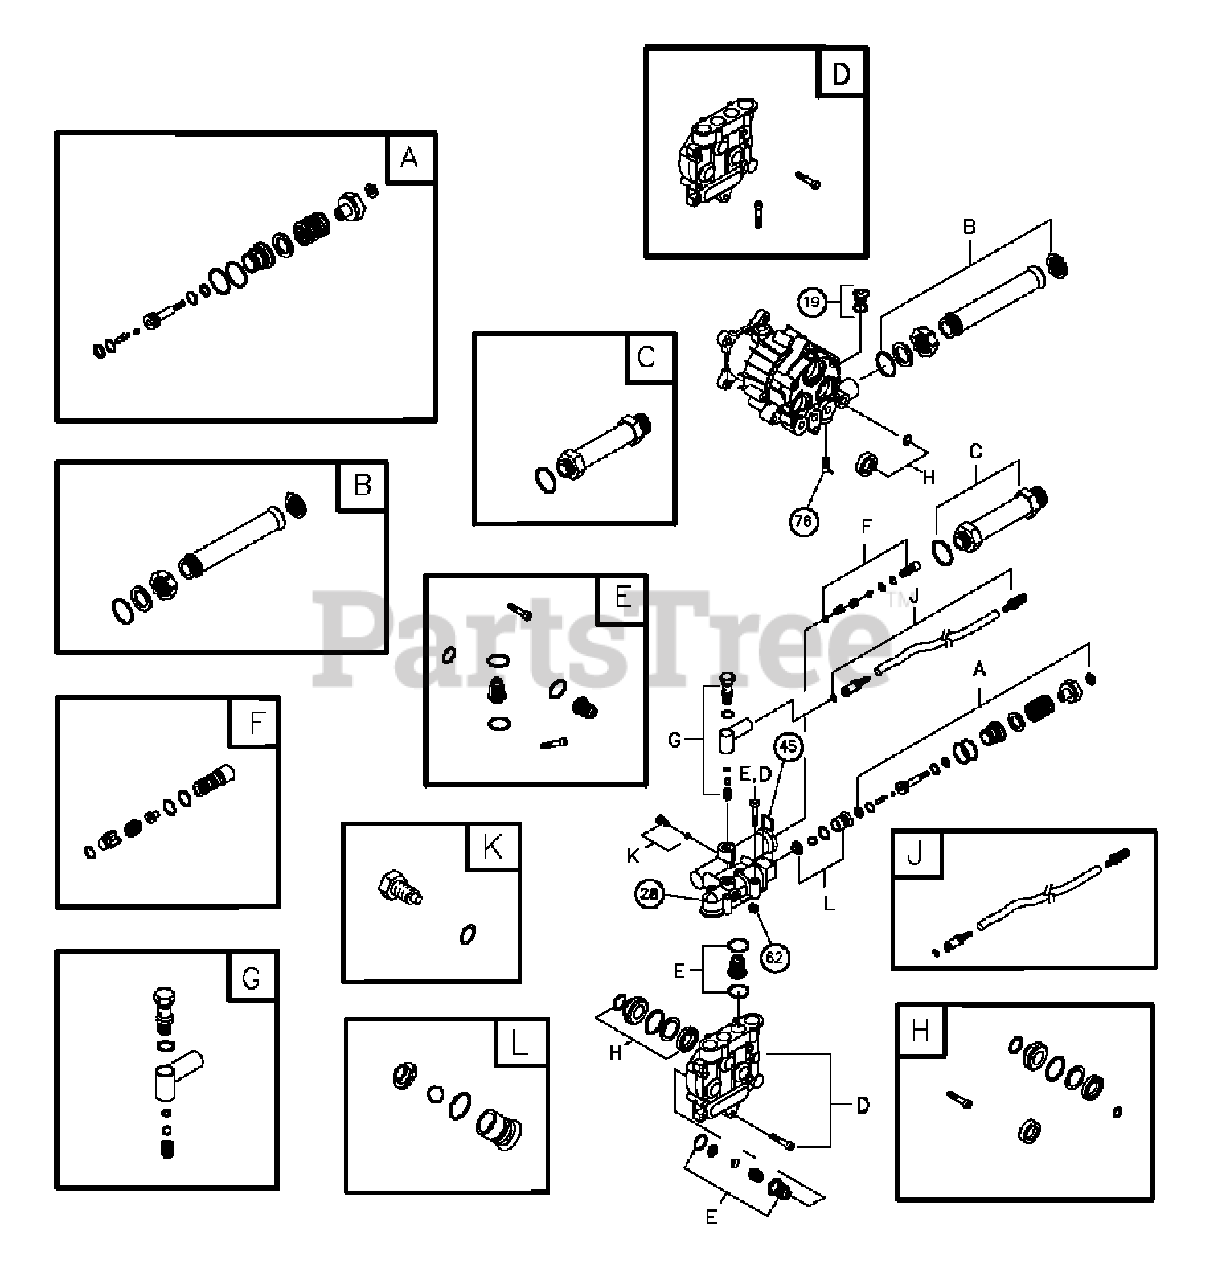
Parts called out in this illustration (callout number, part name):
19	CAP, Oil
28	MANIFOLD
62	CAP, 1/8
76	RELIEF, Thermal
A	* KIT, UNLOADER STEM
B	* KIT, WATER INLET, ANODIZED
C	* KIT, OUTLET, ANODIZED
D	* KIT, HEAD BRASS
E	* KIT, CHECK VALVES
F	* KIT, INLET CHECK
G	* KIT, CHEMICAL INJECTION
H	* KIT, SEAL SET
J	* KIT, CHEMICAL HOSE
K	* KIT, PIPE FITTING
L	* KIT, UNLOADER SEAT
